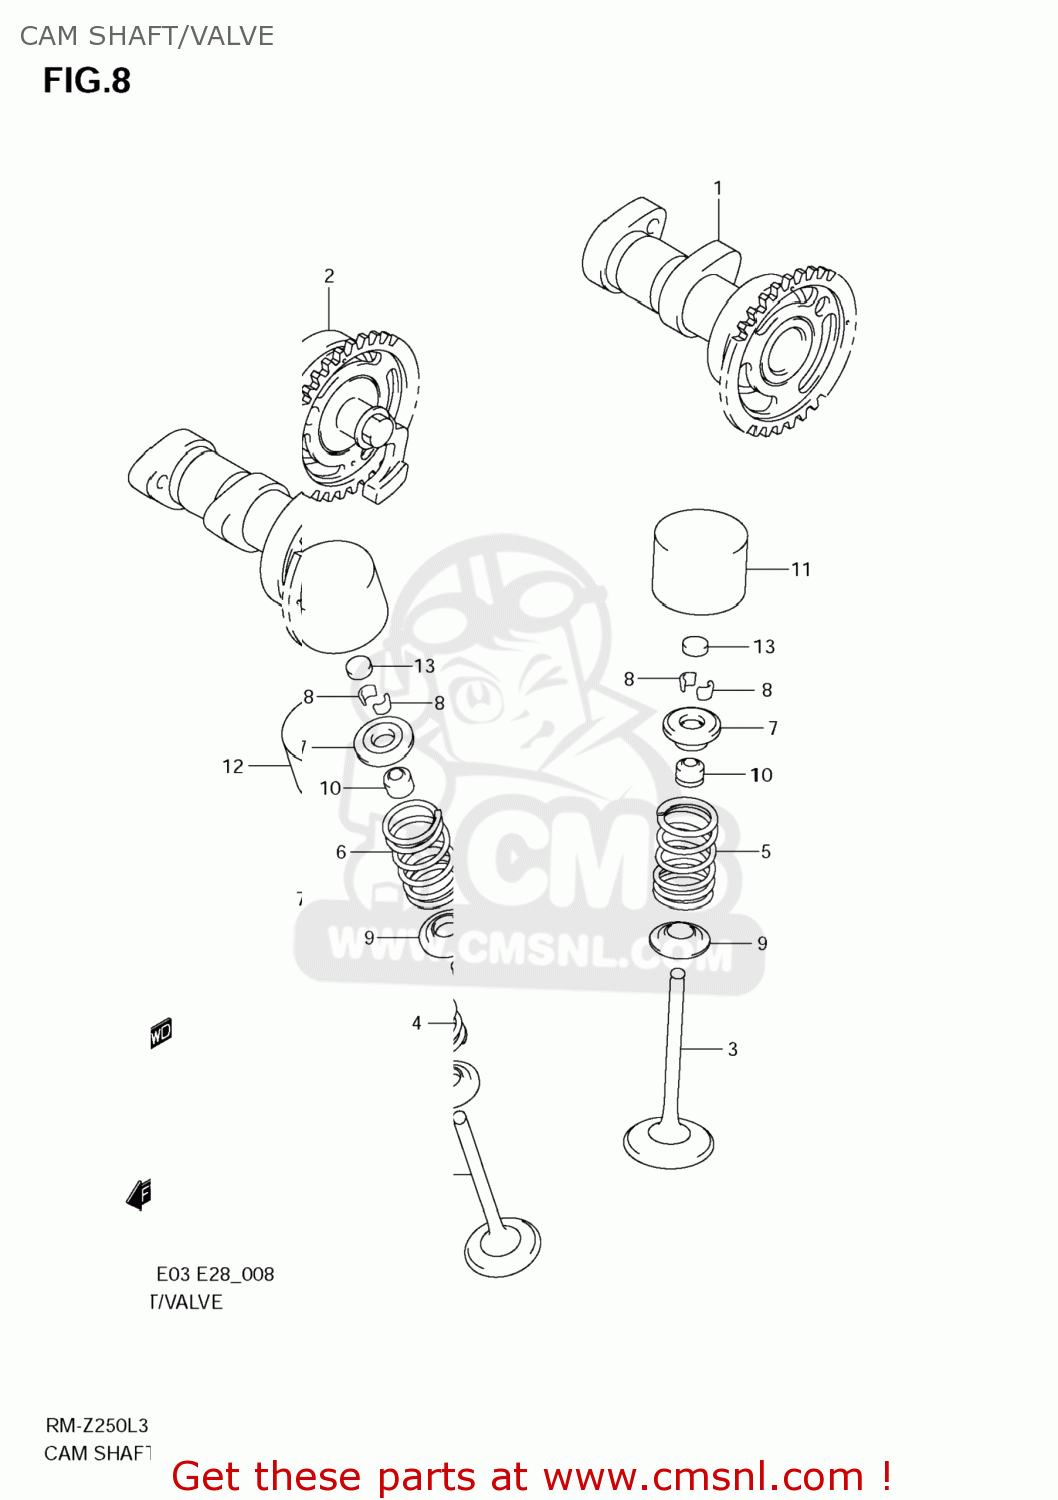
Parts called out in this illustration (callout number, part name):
1	CAMSHAFT,INTAKE
2	CAMSHAFT,EXHAUST
3	VALVE,INTAKE
4	VALVE,EXHAUST
5	SPRING,VALVE
6	SPRING,VALVE
7	RETAINER,VALVE SPRING
8	COTTER VALVE
9	SEAT,VALVE SPRING
10	SEAL,OIL(4.5X10X8)
11	TAPPET
12	TAPPET,EXHAUST
13	SHIM,TAPPET
14	SHIM SET,TAPPET
15	CASE,TAPPET SHIM
